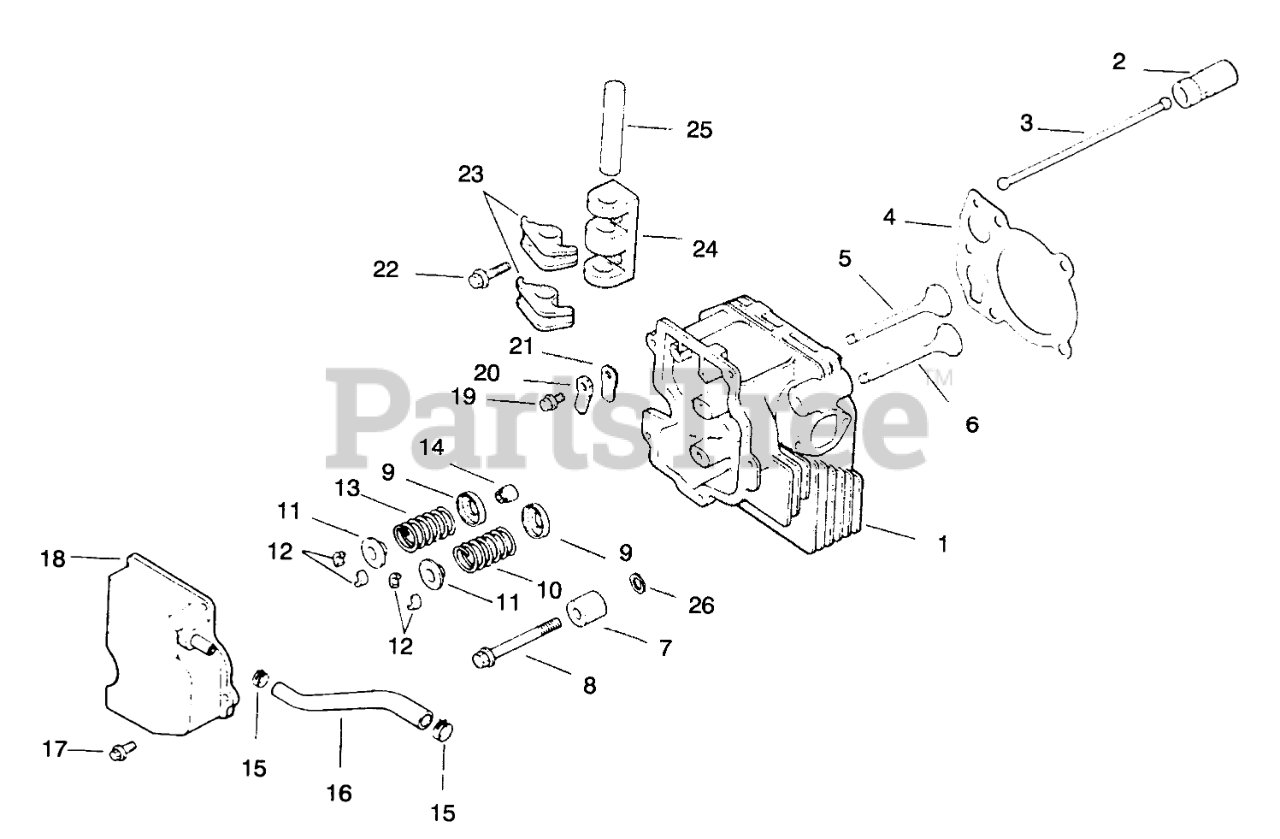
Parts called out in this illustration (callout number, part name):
1	Cylinder Head
2	Lifter-Valve
3	Rod-Push
4	Gasket-Cylinder Head
5	Valve-Intake STD
6	Valve-Exhaust STD
7	Spacer-Head Bolt
8	Screw M10x1.5x80
9	Retainer-Spring
10	Spring-Valve
11	Cap-Spring, Valve
12	Retainer Kit
13	Spring-Valve, Exhaust
14	Seal-Valve Stem
15	Clamp
16	Hose-Breather
17	Screw
18	Cover-Valve w/Nipple
19	Screw
20	Retainer-Reed
21	Reed-Breather
22	Screw
23	Arm-Rocker
24	Bridge-Rocker Arm
25	Shaft-Rocker Arm
26	Washer
